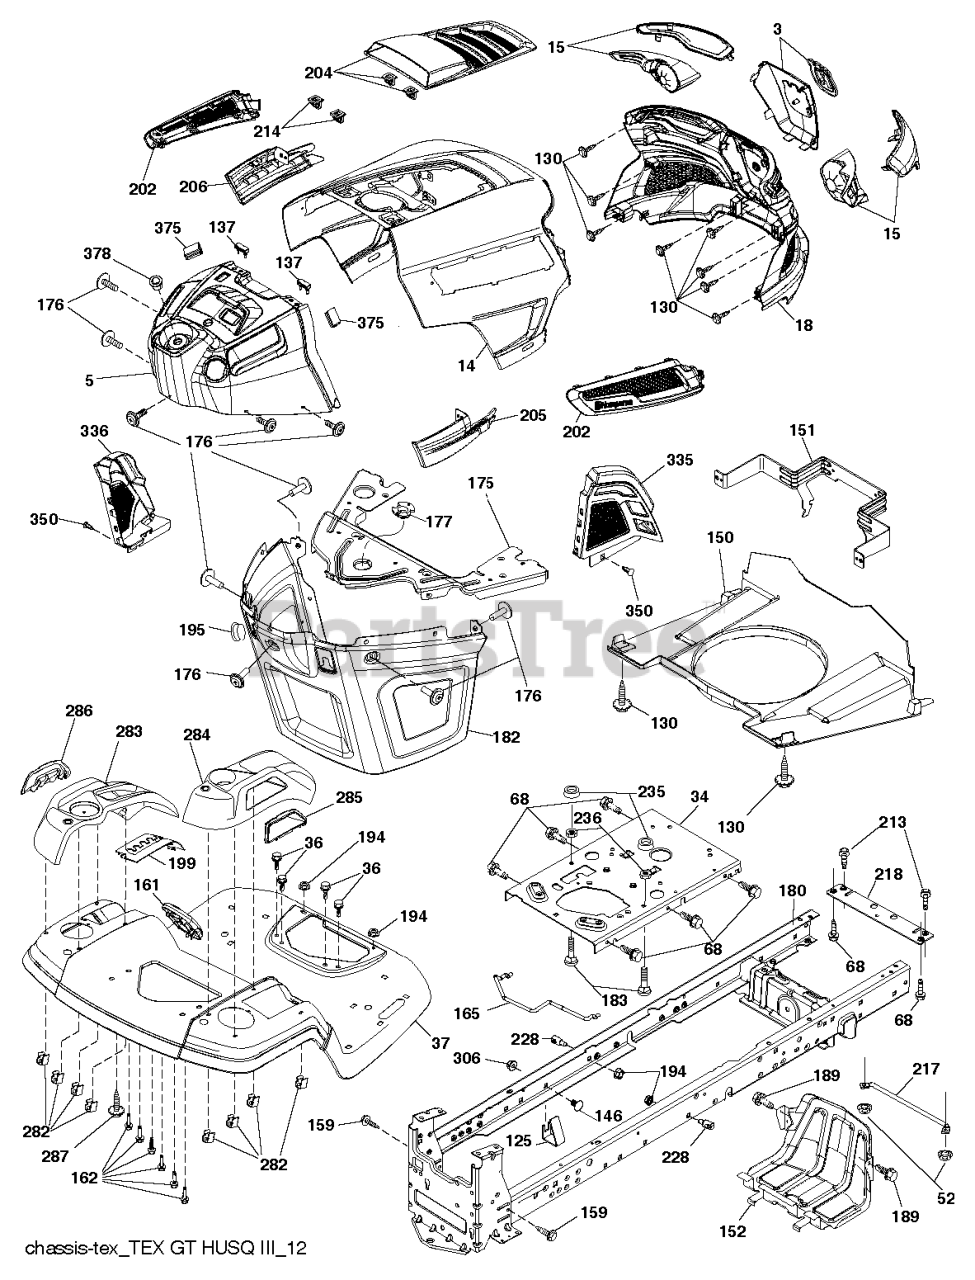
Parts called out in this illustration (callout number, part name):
14	HOOD.ASM.HUSQVARNA.GT.TEX.ORAN
15	Service Kit
34	PLATE.ENGINE.WELDED.CHASSIS
36	SCREW 5/16"
37	FENDER.TLT.FS.W/CPH/FW/RSF.668
125	CLIP.FUEL.LINE
137	BUMPER DASH
146	BOLT.RDHD.SHT.SQNK.3/8-16X5/8
150	AIR.DUCT.GTV.BLACK
151	BRACKET.PIVOT.HOOD.GT.HUSQ.II
152	SHIELD.BROWNING.PNT.GT.V2
159	SCREW, 3/8-16X3/4
161	WINDOW.FUEL.LT.HUSQ.TEX.498
165	SUPPORT.TANK.REAR.W/TEX
175	PLATE.PNT.CROSSMEMBER.HUSQ/PRE
176	SCREW.#10-24X5/8.RN.QU
177	BUSHING STEERING
180	CHASSIS
182	DASH.LOWER.COMMON.12V.ADAPTOR
189	SCREW
195	PLUG.HOLE.DASH.LOWER.12V.BLK
199	PLATE.DECK.LIFT.HUSQ.LT
205	SIDE.TRIM.RH.GT.HUSQ.II
206	SIDE.TRIM.LH.GT.HUSQ.II.GRAY
213	SCREW HEXAGON HEAD SCREW 5/16-
214	CLIP.RETAINER.TINNER.
217	ROD.PIVOT.HOOD
218	X-PIECE.HOOD.STOP.NON/
228	STUD.FASTNER.W/ANTI-ROTATE
228	STUD.W/"D"ANTI-ROTATION
236	NUT.CENTERLOCK.5/16-
282	CLIP.RETAINER.CONSOLE.LT.HUSQ
283	CONSOLE.ASM.LFT.RSF.HUSQ.LT
284	CONCOLE.CNTRL.PDL.HUSQ.LT.498
285	CONSOLE INSERT RH
286	CONSOLE.INSRT.LH.HUSQ.LT.BLACK
287	SCREW 1/4X20
306	NUT LOCK FLG 3/8-16 UNC
335	COVER.LOWER.DASH.RH.BLACK
336	COVER-LH.LOWER.DASH.GT2.BLACK
350	CLIP.X-MAS.TREE
375	BUMPER CLIP-ON. DASH 1"
378	BUSHING FLANGE; PLASTIC
